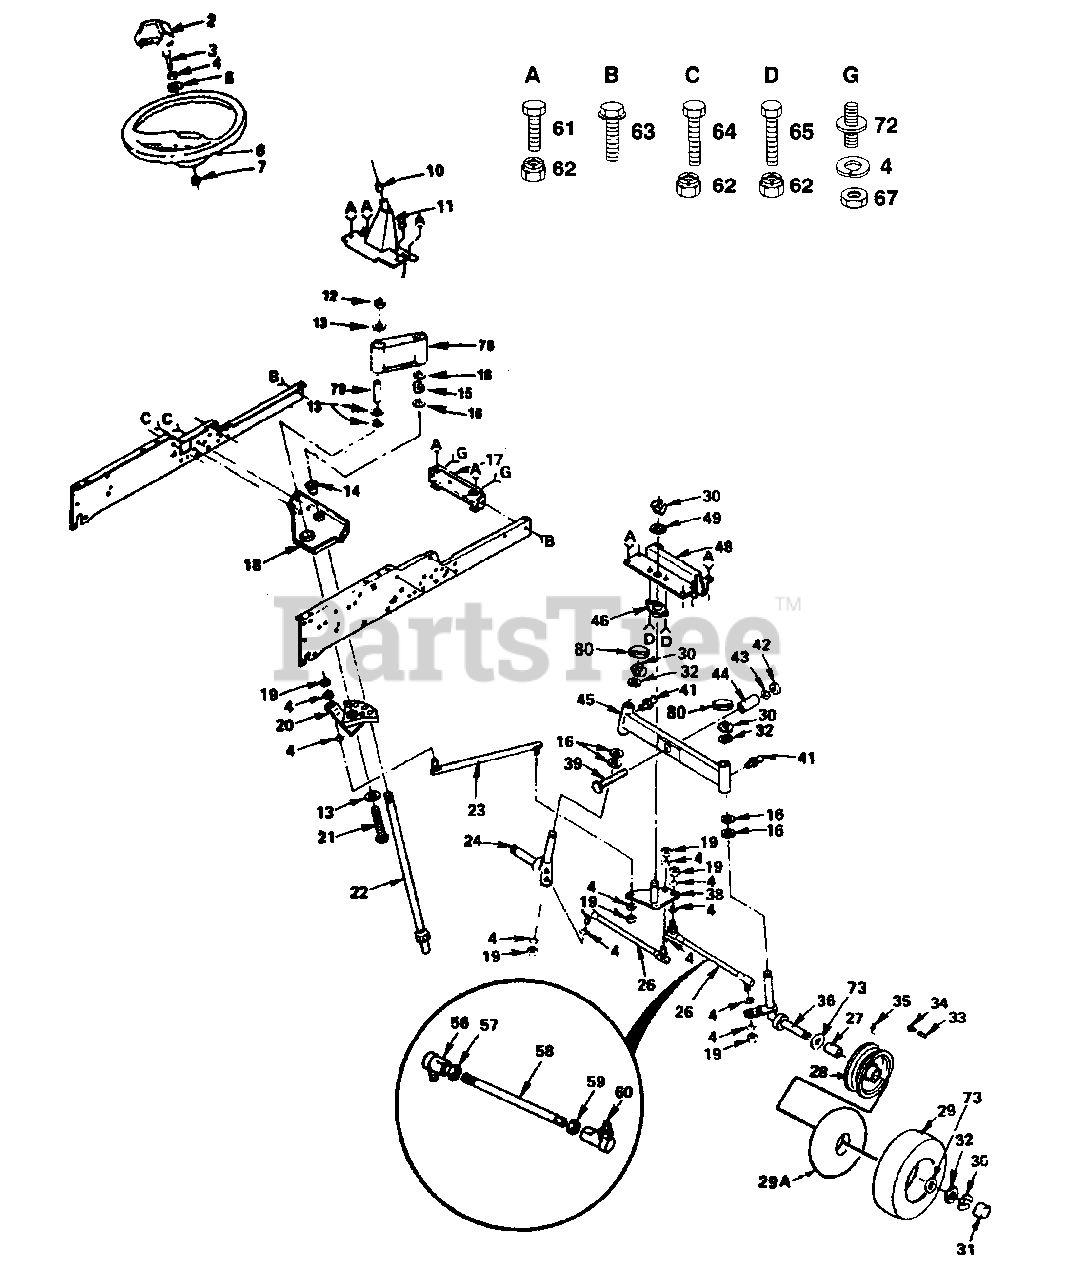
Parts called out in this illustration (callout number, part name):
2	Cap, Steering Wheel (AYP part number)
3	Bolt, Hex 3/8-16 x 1 Grade 5 (AYP part number)
4	Washer, Lock 3/8 (AYP part number)
5	Washer 13/32 x 2-3/8 x 8 Gauge (AYP part number)
6	Wheel, Steering (AYP part number)
7	Adapter, Steering (AYP part number)
10	Bearing (AYP part number)
11	Support Assembly, Dash (AYP part number)
12	Nut, Crownlock 1/2-13 (AYP part number)
13	Washer 17/32 x 1-5/8 x 10 Gauge (AYP part number)
14	Bearing, Flanged (AYP part number)
15	Klip, Ring (AYP part number)
16	Bearing, Thrust (AYP part number)
17	Bracket, Frame Front (AYP part number)
18	Bracket, Support, Steering (AYP part number)
19	Nut, Hex 3/8-24 (AYP part number)
20	Sector Assembly (AYP part number)
21	Bolt, Hex 1/2-13 x 5 Grade 5 (AYP part number)
22	Shaft, Steering (AYP part number)
23	Link, Drag (AYP part number)
24	Spindle, L.H. (AYP part number)
26	Rod, Tie (Inc. Key #56-60) (AYP part number)
27	Bearing (AYP part number)
28	Rim Assembly (AYP part number)
29	Tire (AYP part number)
29A	Tube (Optional, Service Item Only) (AYP part number)
30	Klip, Ring (AYP part number)
31	Cap, Axle (AYP part number)
32	Washer 25/32 x 1-5/8 x 16 Gauge (AYP part number)
33	Cap, Valve (AYP part number)
34	Stem, Valve (AYP part number)
35	Fitting, Grease (AYP part number)
36	Spindle, R.H. (AYP part number)
38	Bellcrank Assembly (AYP part number)
39	Bolt, Hex 5/8-11 x 2-3/4 Grade 5 (AYP part number)
41	Fitting, Grease (AYP part number)
42	Nut, Hex 5/8-11 (AYP part number)
43	Washer, Lock 5/8 (AYP part number)
44	Tube, Pivot, Axle (AYP part number)
45	Axle Assembly, Front (AYP part number)
46	Bushing, Bellcrank (AYP part number)
48	Bracket, Axle (AYP part number)
49	Washer 29/32 x 1-1/4 x 16 Gauge (AYP part number)
56	Joint, Tie Rod, L.H. Thread (AYP part number)
57	Nut, Hex Jam 3/8-24 L.H. (AYP part number)
58	Rod, Tie (AYP part number)
59	Nut, Hex Jam 3/8-24 (AYP part number)
60	Joint, Tie Rod, R.H. Thread (AYP part number)
61	Bolt, Hex 3/8-16 x 3/4 (AYP part number)
62	Nut, Crownlock 3/8-16
63	Screw, Hex Washer Thd. Rolling 3/8-16 x 3/4 (AYP part number)
64	Bolt, Hex 3/8-16 x 1 Grade 5 (AYP part number)
65	Bolt, Hex 3/8-16 x 1 (AYP part number)
67	Nut, Hex 3/8-16 (AYP part number)
72	Pin Mounting, Idler Bracket (AYP part number)
73	Washer 25/32 x 1-1/4 x 16 Gauge (AYP part number)
76	Collar Weld Assembly (AYP part number)
79	Tube (AYP part number)
80	Dust Cap Cover (AYP part number)
